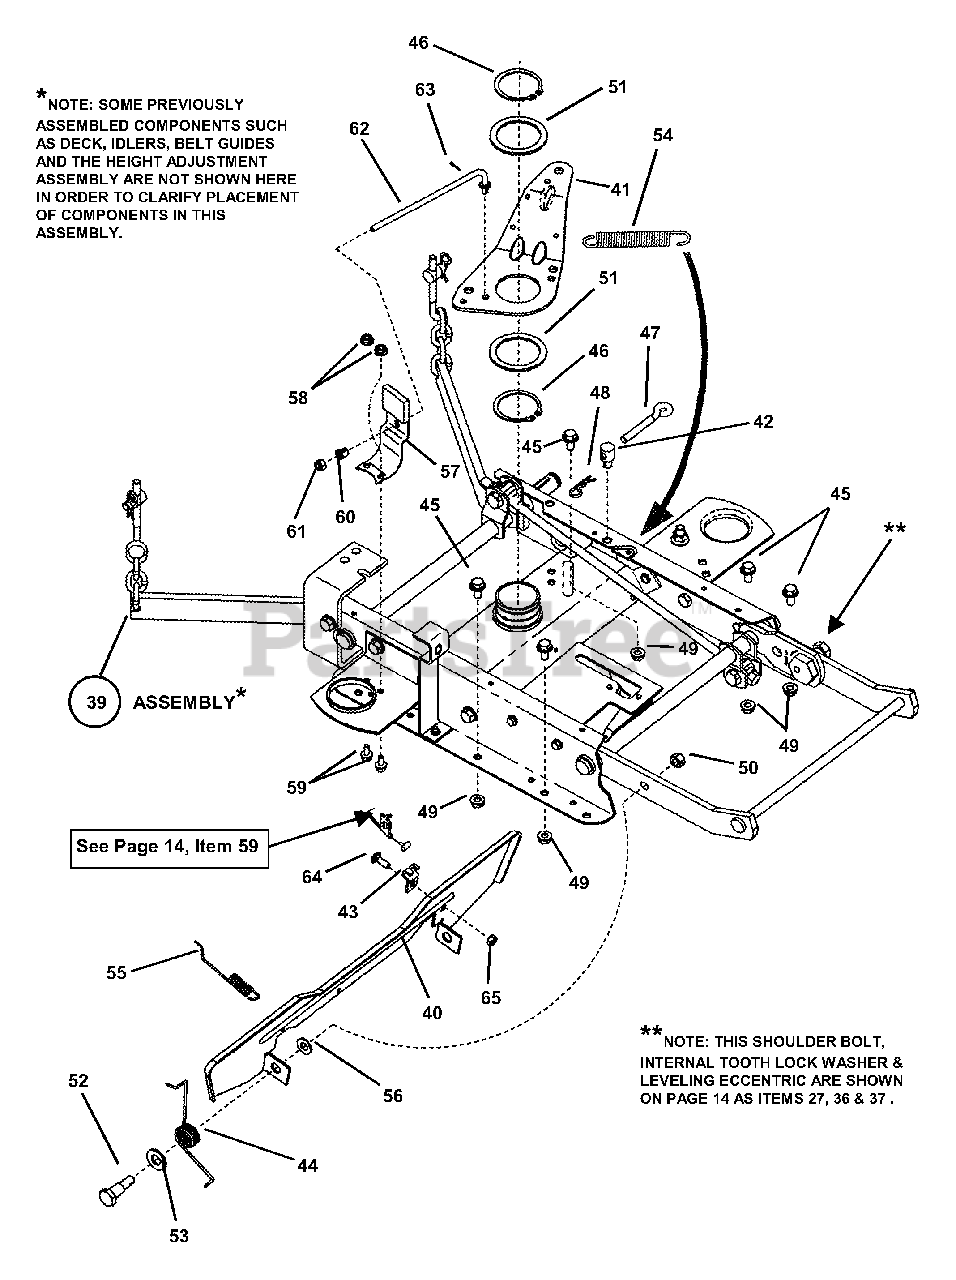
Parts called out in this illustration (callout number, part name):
39	ASSEMBLY, Rail
40	PEDAL, Blade Stop Control
41	ARM, Idler
42	SWIVEL, Adjustable (with 5/16-18 internal thread)
43	CLIP, Cable
44	SPRING, Pedal
45	BOLT, 5/16-18 x 5/8" Hex Flange Lock
46	RING, 2" External Retaining
47	EYE-BOLT, 5/16-18 x 3"
48	HAIRPIN, 3/32 x 1-1/2"
49	NUT, 5/16-18 Hex Flange Lock
50	NUT, 3/8-24 Hex Center Lock
51	WASHER, 2" I.D. Nylon
52	BOLT, 3/8-24 x 9/16" Shoulder
53	WASHER, 1/2" Flat
54	SPRING, Return
55	SPRING, Latch
56	WASHER, 3/8" Flat
57	SPRING BRAKE PAD
58	NUT, 1/4-20 Hex Flange Lock
59	BOLT, 1/4-20 x 1/2" Hex Flange Lock
60	BUSHING, 3/8" Snap Plastic
61	NUT, 1/4-20 Hex Nyloc
62	LINK, Spindle Brake
63	PIN, 1/16 x 1/2" Cotter
64	BOLT, 1/4-20 x 3/4" Round Head Square Neck, Grade 5
65	NUT, 1/4-20 Hex, Grade 5 or B
